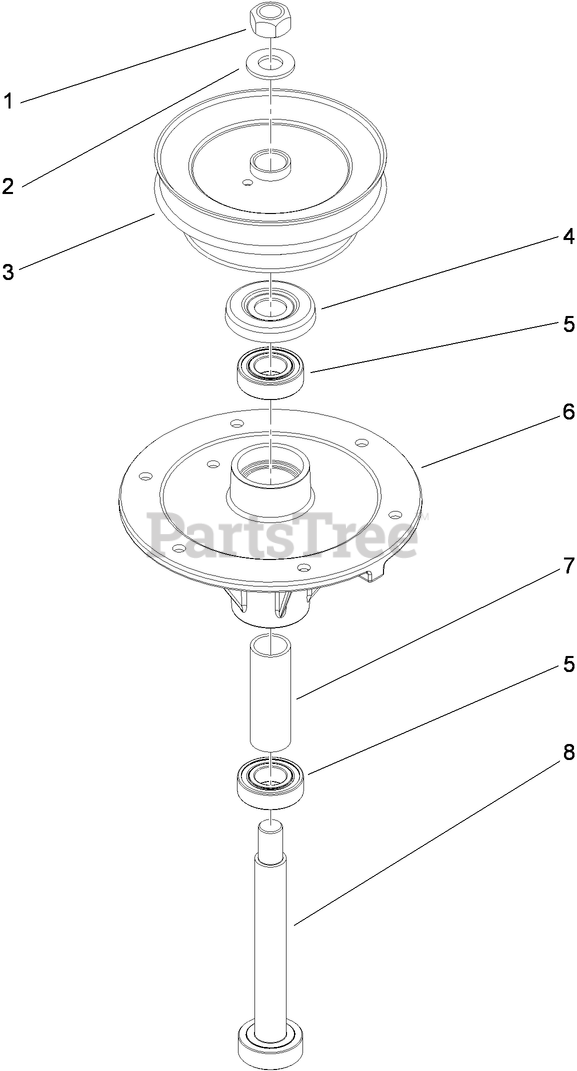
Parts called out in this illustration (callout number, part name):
1	NUT-HEX
2	WASHER
3	PULLEY AND HUB ASM
4	SHIELD-BEARING
5	BEARING-BALL
6	HOUSING-SPINDLE
7	SPACER-BEARING
8	SHAFT-SPINDLE
